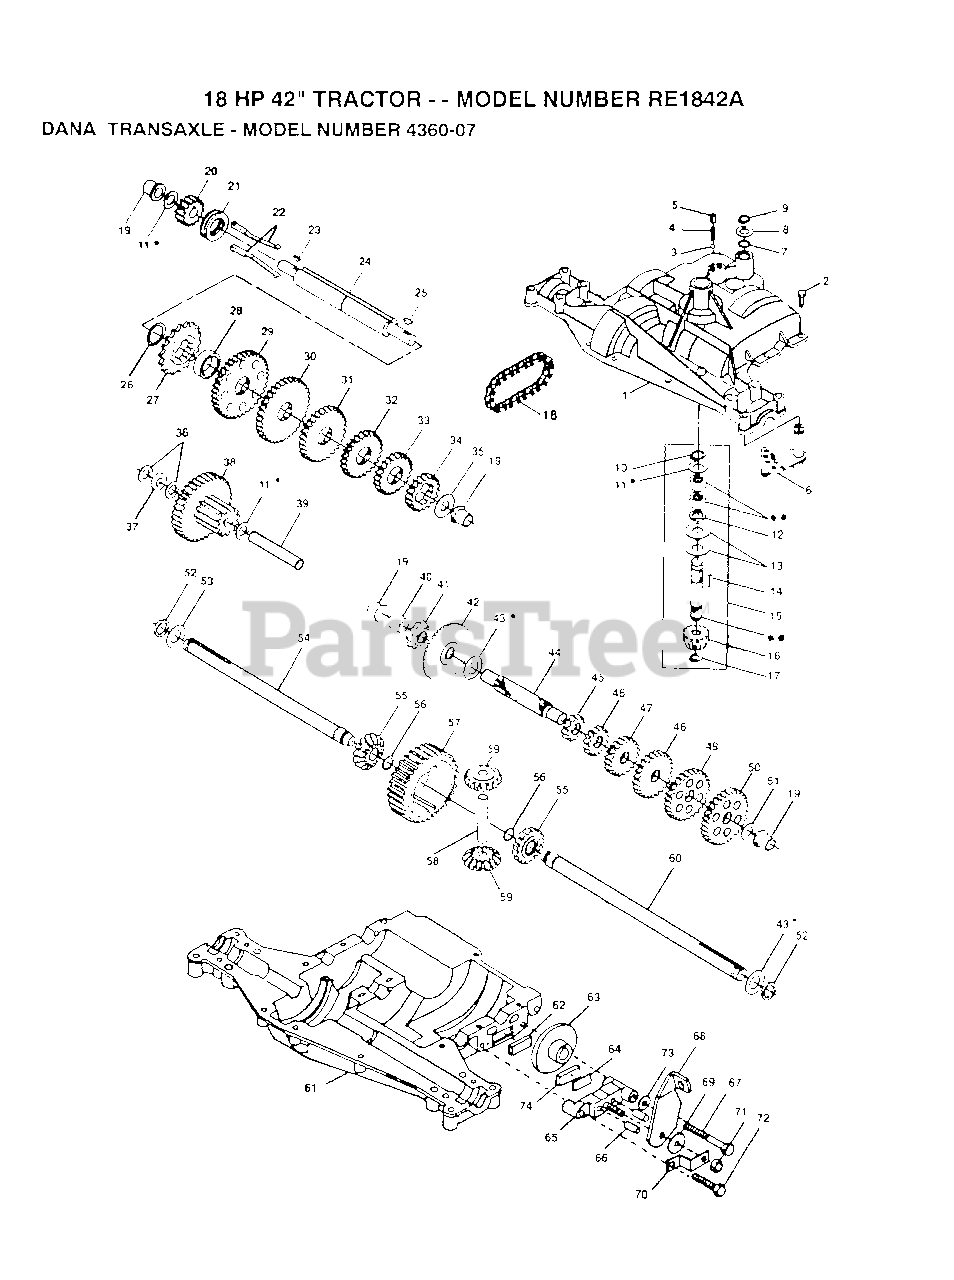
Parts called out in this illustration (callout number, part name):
1	HOUSING UPPER
3	BALL DETENT
4	SPRING, DETENT
5	SCREW, SET
6	ASSY SHIFTER
8	WASHER PLAIN
9	RING RETAINING
10	RING RETAINING
11	WASHER PLAIN
13	WASHER, PLAIN .632 X 1.38 X .046
14	KEY WOODRUFF #9
15	ASSY KIT INPUT SHAFT
16	PINION, BEVEL, 14 TEETH
17	RING, RETAINING
18	CHAIN, 24 PITCHES
19	BEARING, FLANGE
20	GEAR SPUR, 14 TEETH
21	COLLAR CLUTCH
22	KEY CLUTCH
23	KEY WOODRUFF #3
24	SHAFT INTERMEDIATE
25	KEY, WOODRUFF, #61
26	RING, RETAINING
27	SPROCKET, 18 TEETH
29	GEAR, SPUR, 37 TEETH
30	GEAR, SPUR, 35 TEETH
31	GEAR, SPUR, 30 TEETH
32	GEAR, SPUR, 25 TEETH
33	GEAR, SPUR, 22 TEETH
35	WASHER, PLAIN .640 X 1.37 X .061
36	WASHER, PLAIN .632 X 1.00 X .026
37	SPACER .630 X 1.00 X .169
38	ASSY GEAR COMB 12&35 TEETH
39	SHAFT IDLER
40	SPACER .635 X .875 X .755
41	SPROCKET, 9 TEETH
42	GEAR, BEVEL, 42 TEETH
43	WASHER PLAIN
44	SHAFT, DRIVE
45	GEAR, SPUR, 12 TEETH
46	GEAR SPUR, 15 TEETH
47	GEAR, SPUR, 20 TEETH
48	GEAR, SPUR, 25 TEETH
49	GEAR, SPUR, 28 TEETH
50	GEAR, SPUR, 31 TEETH
51	WASHER, PLAIN .632 X 1.00 X .060
53	WASHER PLAIN
54	AXLE LEFT HAND
55	GEAR, MITER, 15 TEETH
56	RING, RETAINING
57	GEAR, SPUR, 32 TEETH
58	SHAFT, CROSS
59	GEAR, MITER, 15 TEETH
60	AXLE, R.H.
61	HOUSING LOWER
62	PUCK, FRICTION
63	DISC, BRAKE
65	JAW, BRAKE
66	PIN, DOWEL
67	SCREW TAPPING
68	LEVER, ACTUATING
69	WASHER, PLAIN .321 X 1.00 X .055
70	BRACKET, ANTI-ROTATION
71	LOCKNUT 5/16-24
72	SCREW TAPPING
73	WASHER PLAIN
74	PUCK, FRICTION
